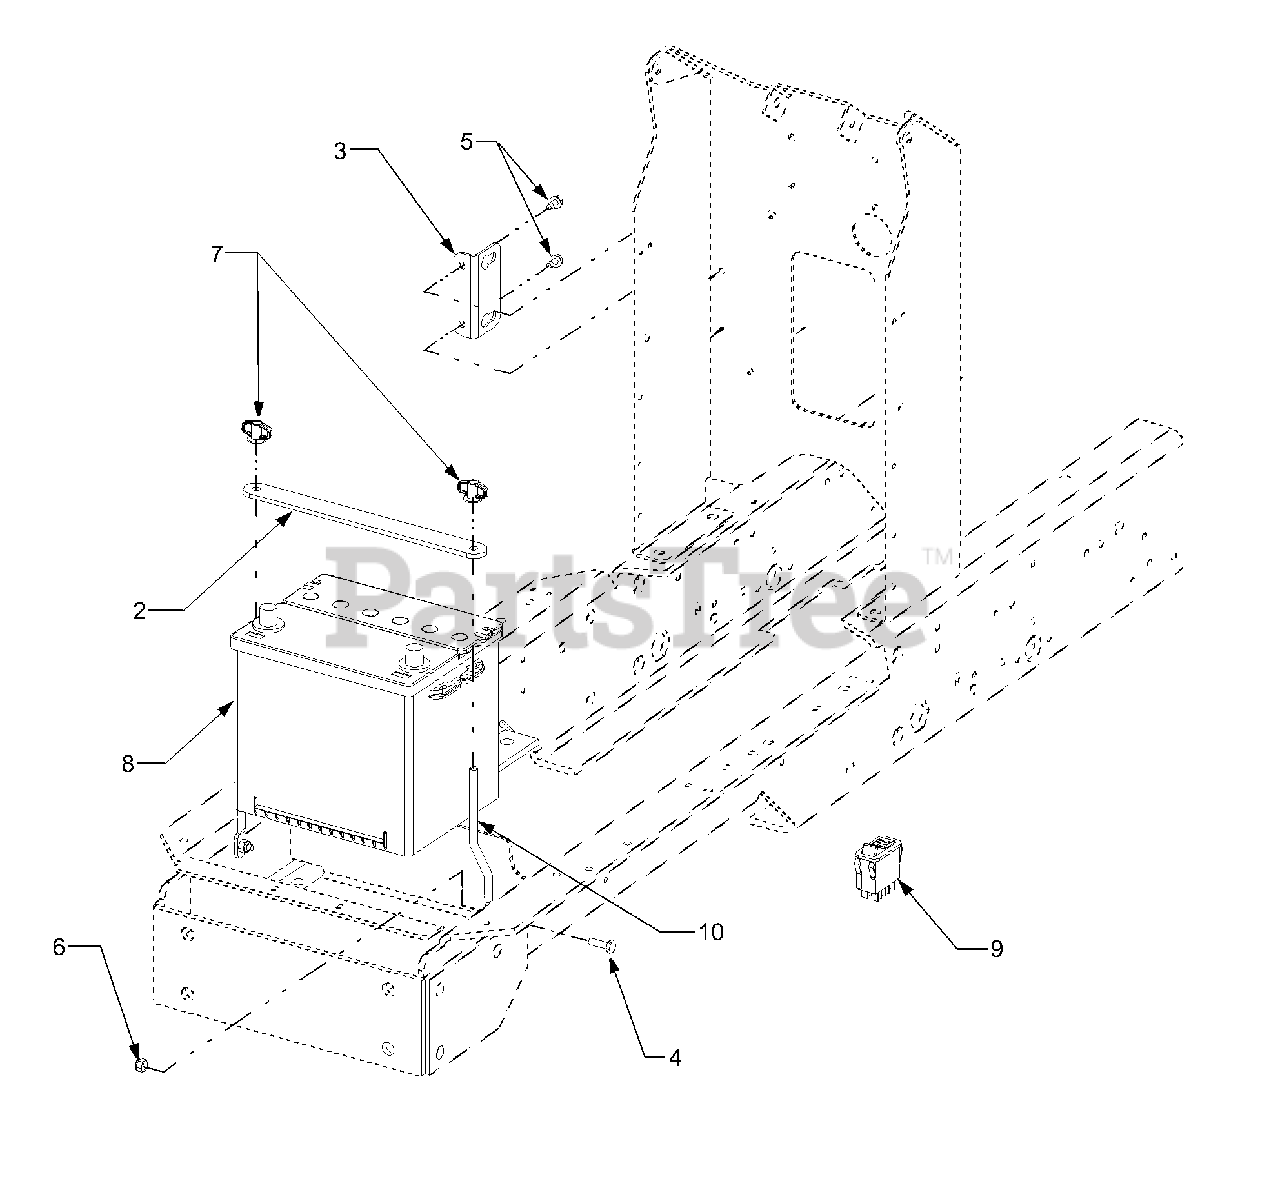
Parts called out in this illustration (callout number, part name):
2	Strap, Battery Holddown
5	Screw, Hex Wash Hd. Tapp 1/4-20 x .5
6	Nut, Hex Nylon Insert Lock, 1/4-20
7	Nut, Wing w/Bell Washer, 5/16-18
8	Battery, 500 cca Dry
9	Switch, PTO Reverse Override
10	Rod, Battery Holddown
